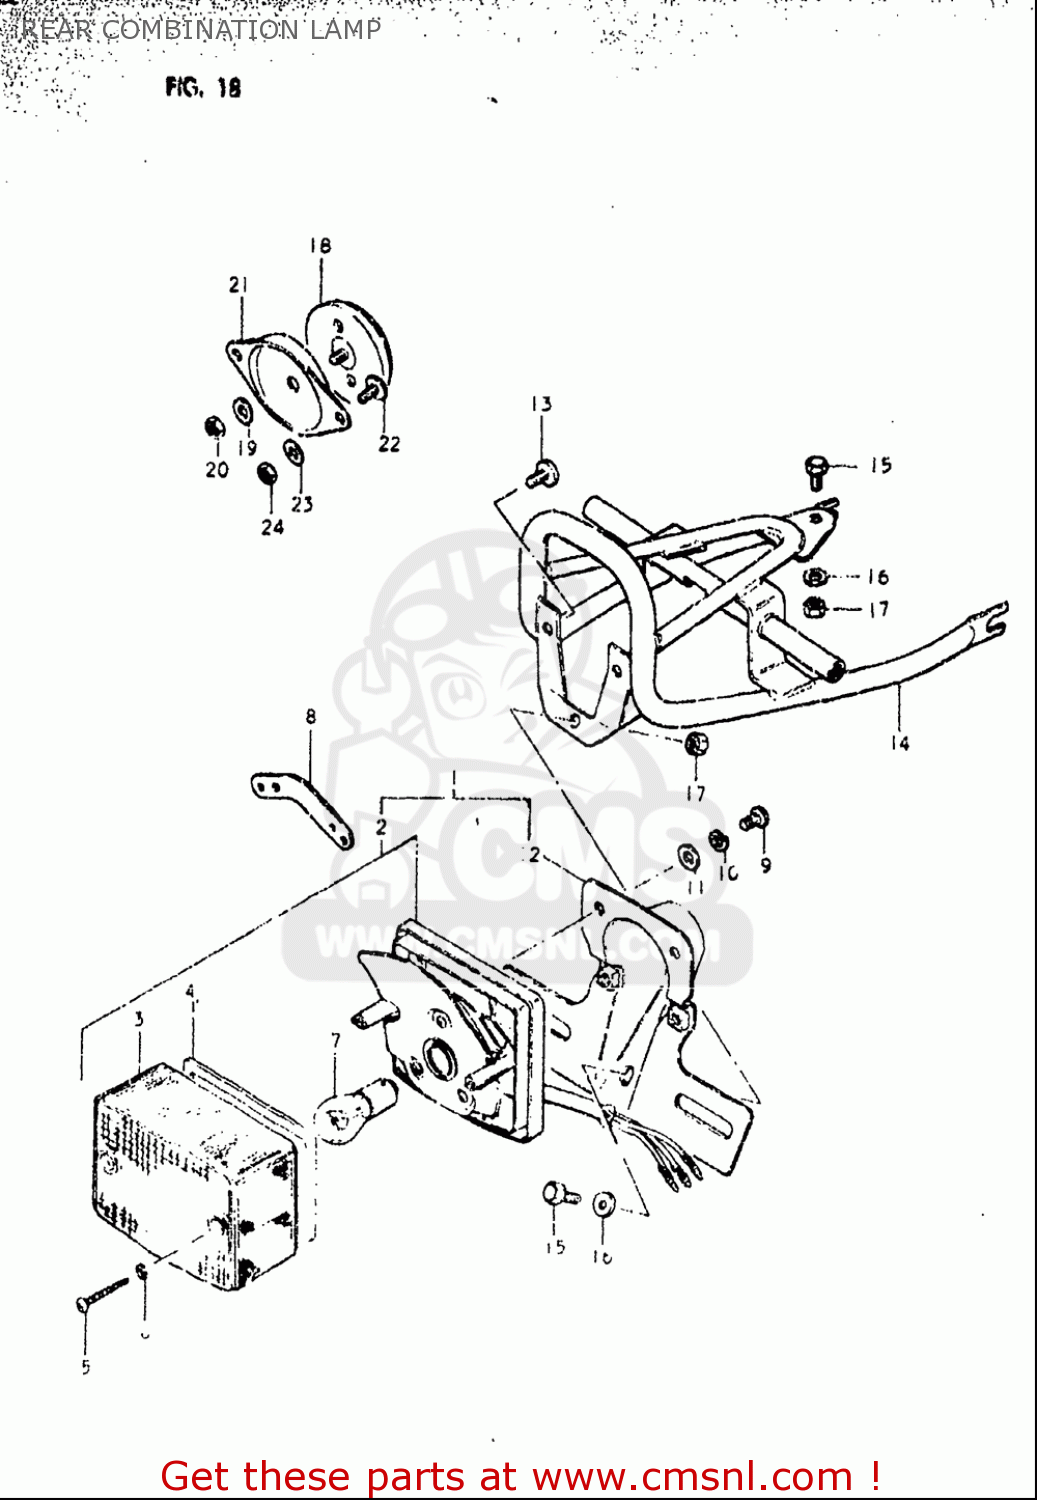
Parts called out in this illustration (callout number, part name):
3	LENS
4	GASKET (NAS)
5	SCREW
6	GASKET (NAS)
7	BULB(6V32/3CP,STANLEY)
9	SCREW
10	WASHER,LOCK
11	WASHER
13	SCREW
15	BOLT
16	WASHER
17	NUT
18	REFLEX REFLECTOR,RR
19	WASHER
20	NUT
22	SCREW
23	WASHER
24	NUT
